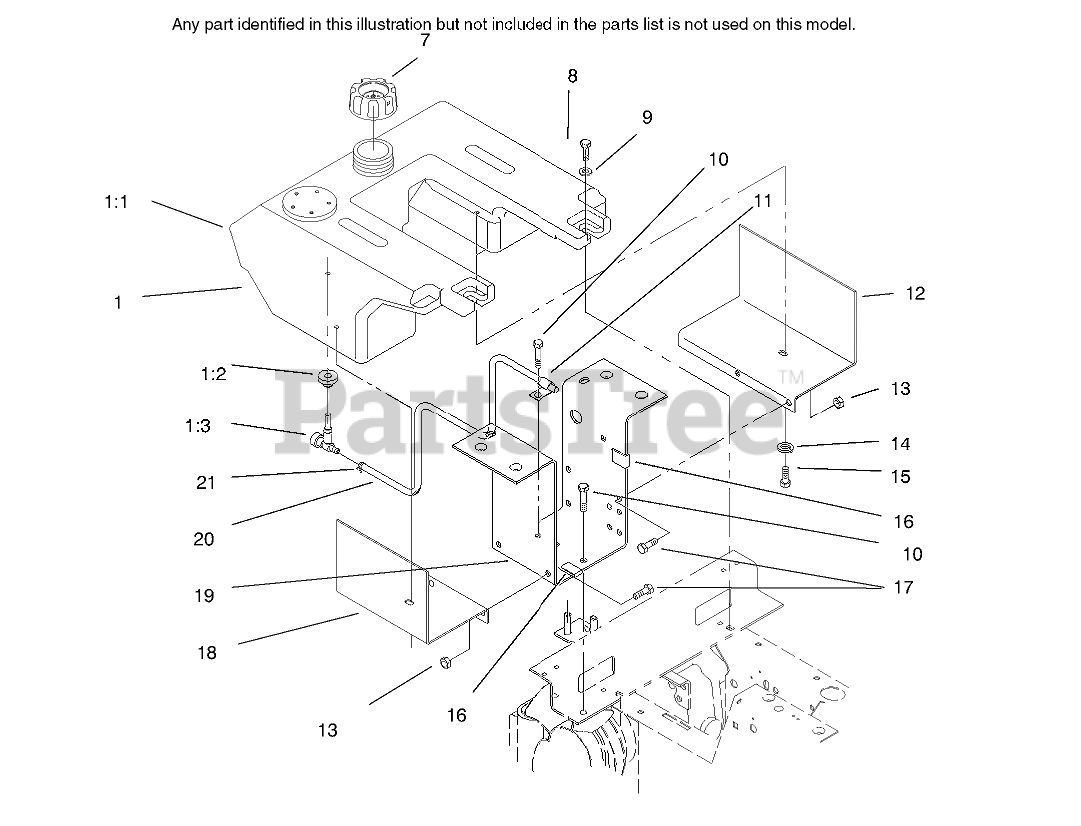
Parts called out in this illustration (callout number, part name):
1	TANK-FUEL
1:2	VALVE-FUEL
1:3	BUSHING
7	GAS CAP ASM
8	SCREW-HWHTF
9	WASHER-FLAT
10	SCREW-HH, LOCK
11	CLIP
12	Bracket-Support
13	NUT-LOCK, NI
14	WASHER-LOCK
15	SCREW-HH
16	CLIP-CABLE
17	SCREW-HH
18	Bracket-Support
19	Bracket-Fender Support
20	Line-Fuel 62"
21	CLAMP-HOSE
